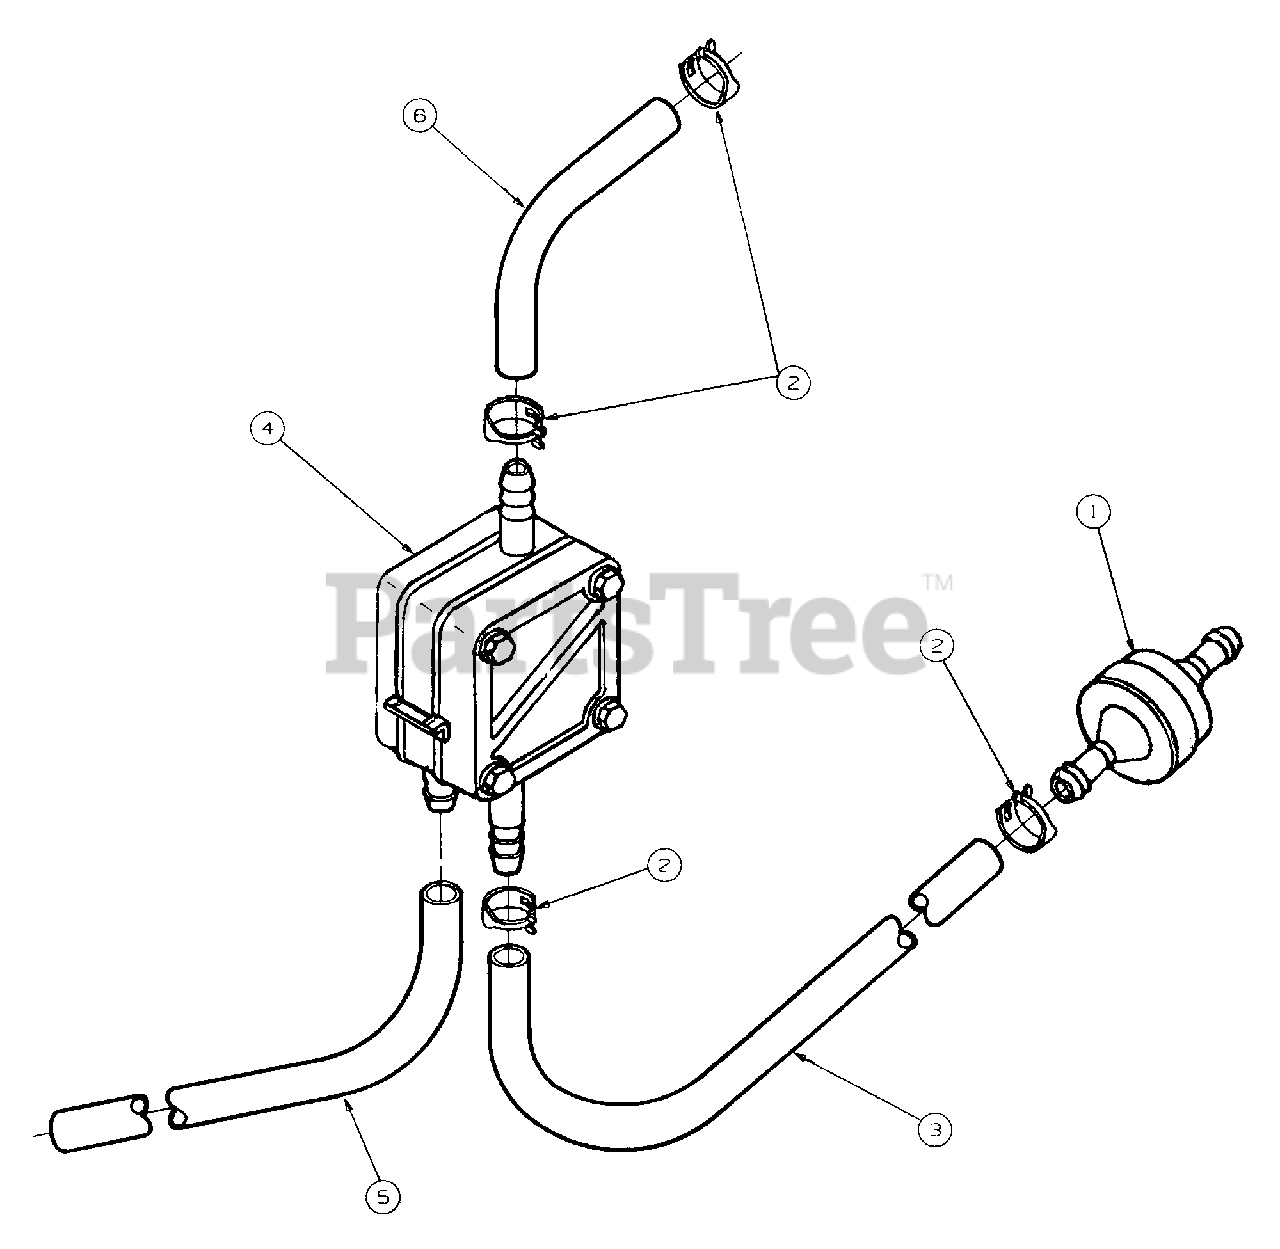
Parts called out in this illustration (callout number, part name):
1	Filter, Fuel
2	Clamp, Hose
3	Hose, Inlet Fuel 1/4 x 230 mm
5	Hose, Pulse Line Fuel 1/4 x 166 mm
6	Hose, Outlet Fuel 1/4 x 54 mm
